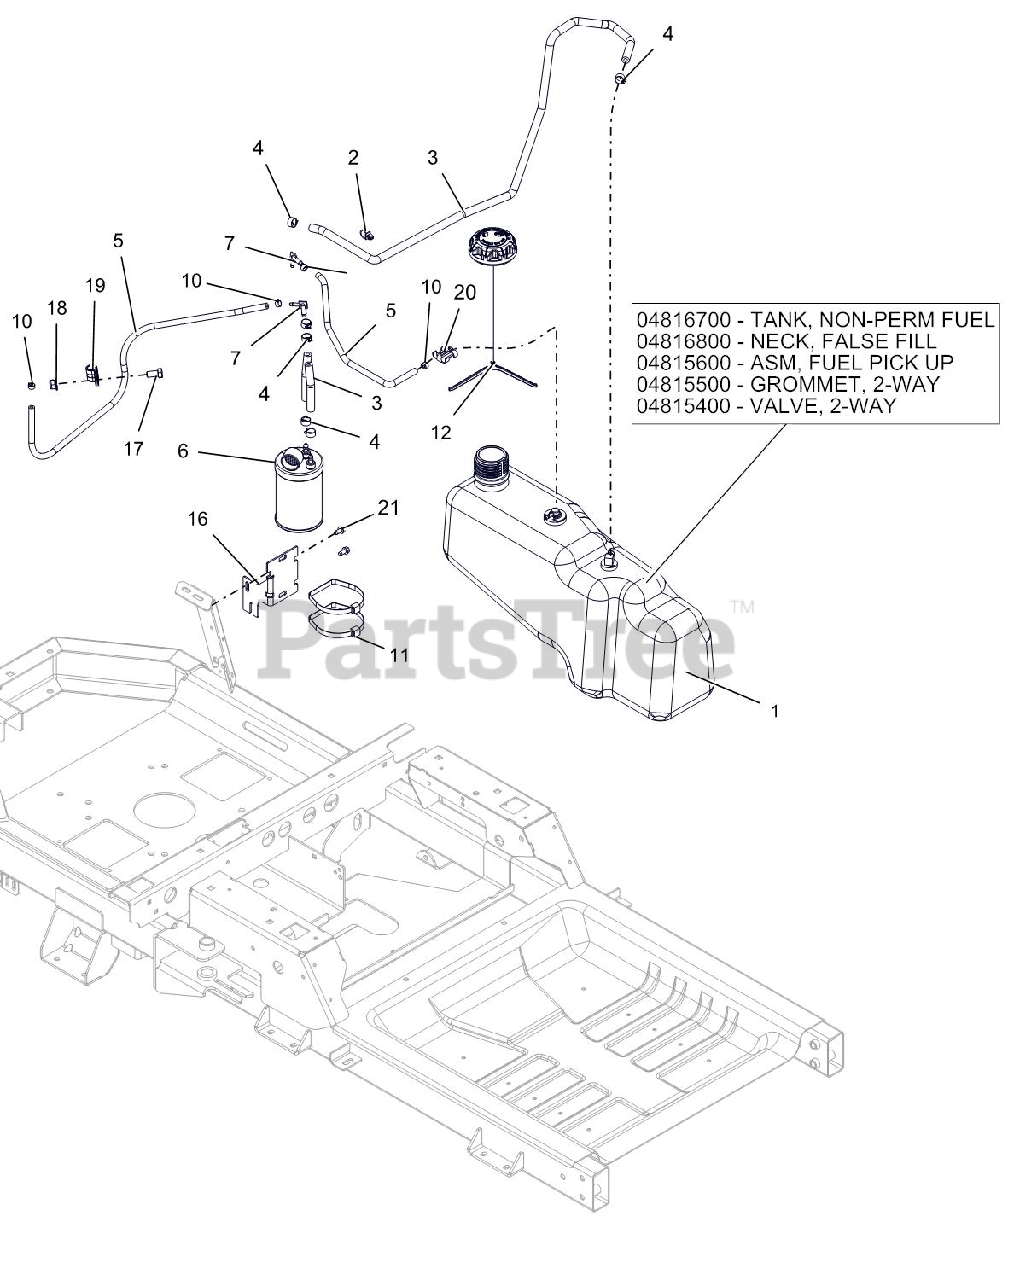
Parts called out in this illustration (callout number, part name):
1	GROMMET, 2-WAY
1	VALVE, 2-WAY
1	ASM,TANK NON-PERM FUEL
1	NECK, FALSE FILL ZOOM/ZT
1	ASM, FUEL PICK-UP ZOOM/ZT 2015
1	TANK, ZOOM/ZT NON-PERM, FUEL
2	ROUTING CLIP (1/2" ID)
3	HOSE, .25 LOW-PERM BULK GAS
4	CLAMP, FUEL LINE
5	HOSE, .188 LOW-PERM BULK GAS
6	CARBON CANISTER, 300CC
7	FITTING-3/16X1/4 90DEGREE VAC
10	CLAMP-HOSE, SPRING .188
11	P-PLASTIC TIE STRAP LARGE
12	CAP, FUEL VENT-IN 2.25" RATCH.
16	BRKT, CARB CANISTER MOUNT
17	BLT-HEX .38-16X.75 GR5 YWZC
18	NUT-LK-NYL-FLG .38-16 YWZC
19	CLAMP, CUSHIONED STEEL
20	CLIP, T, .38-.50
21	SCR-TAP .25-20X.50 HWH TR YWZ
